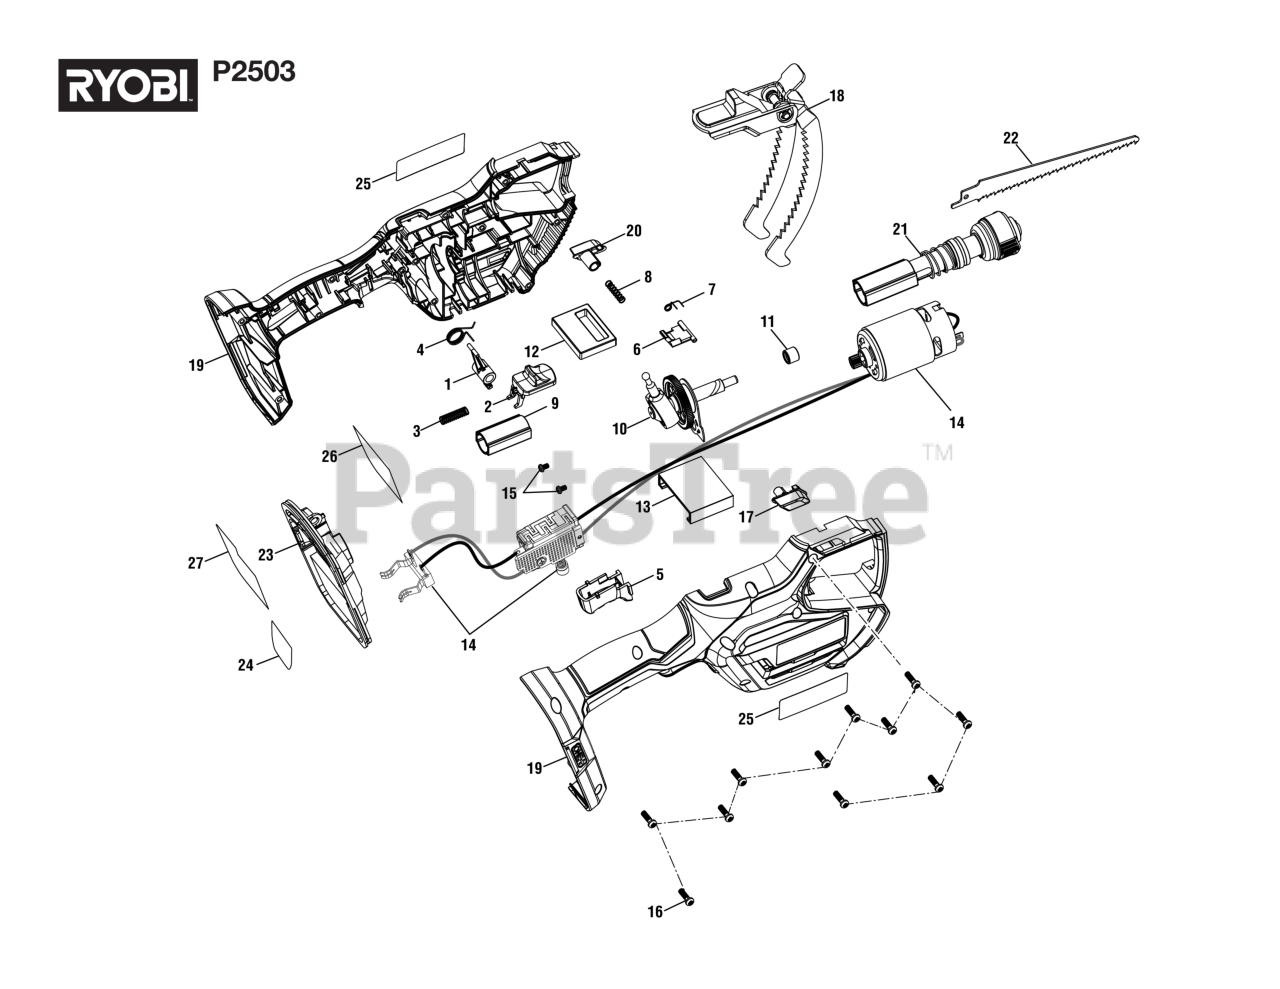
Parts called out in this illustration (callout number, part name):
1	Lock-Out Lever
2	Switch Cover
3	Safety Knob Spring
4	Safety Lever Spring
6	Clamp Release Hook
7	Hook Spring
8	Compression Spring
9	Saw-Bar Rear Bushing
10	Reciprocate Mechanism Assembly
11	Needle Bearing
12	Counter Mass and Pin Assembly
13	Mass Cage
14	Motor, Switch, and Battery Contact Assembly
15	Screw (M3 x 5 mm, Pan Hd.)
16	Screw (M3.5 x 12 mm, Pan Hd.)
17	Clamp Release Button (Right)
18	Clamp Assembly
19	Housing Assembly (Inc. Key Nos. 25 & 26)
20	Clamp Release Button (Left)
21	Saw-Bar Assembly
23	Battery Foot Assembly (Inc. Key No. 24)
24	Warning Label
25	Logo Label
26	Data Label/Battery Statement
